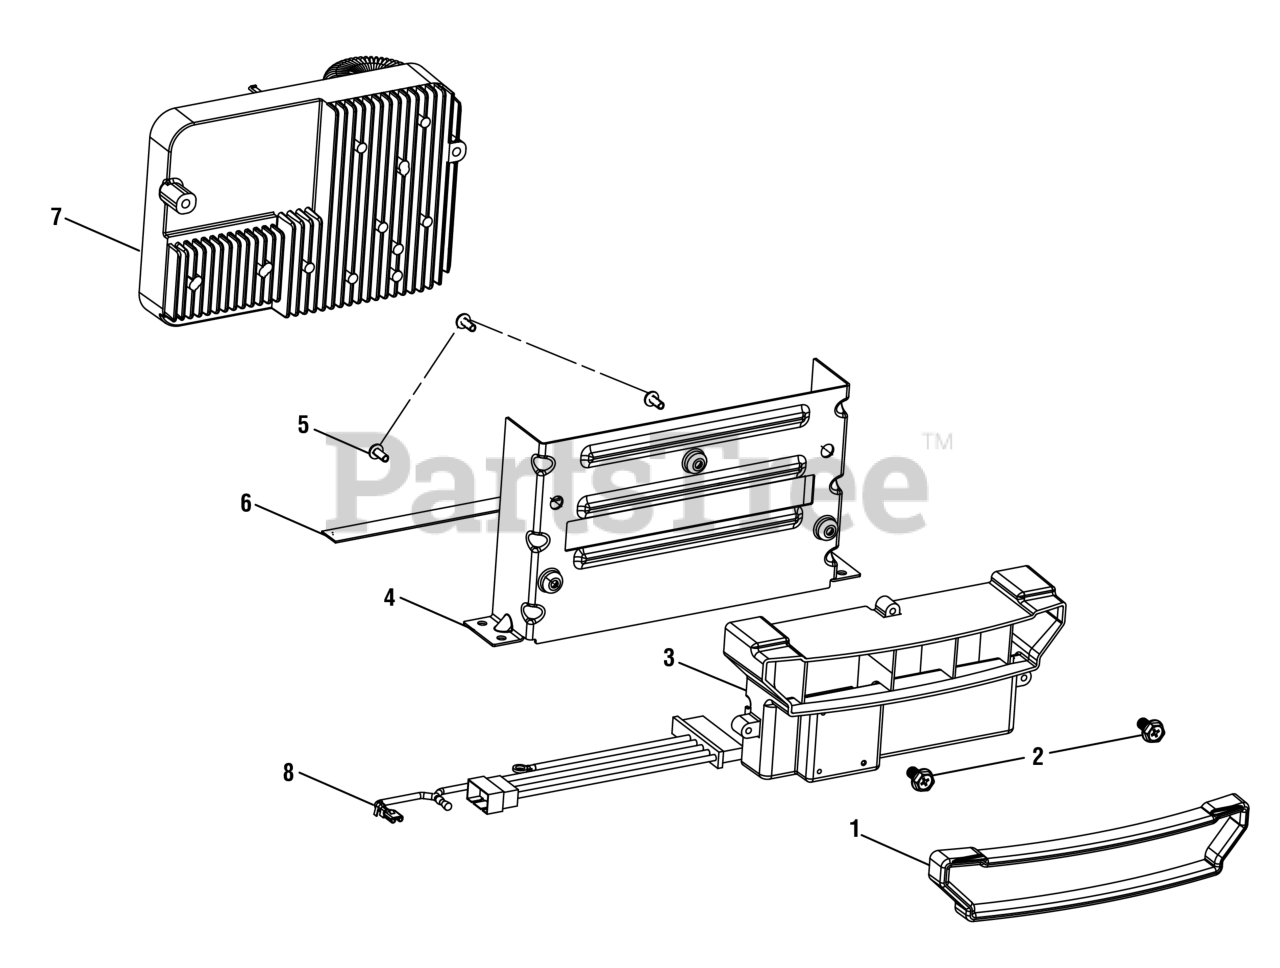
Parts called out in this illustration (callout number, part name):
1	Rubber Trim
2	Bolt (M6 x 12 mm, Hex Hd.)
3	Baffle (Engine Intake)
5	Screw w/Washer (M4 x 10 mm, T20 Torx Button Hd.)
6	Rubber Pad
7	Inverter Module
8	CO Module Wiring Harness
